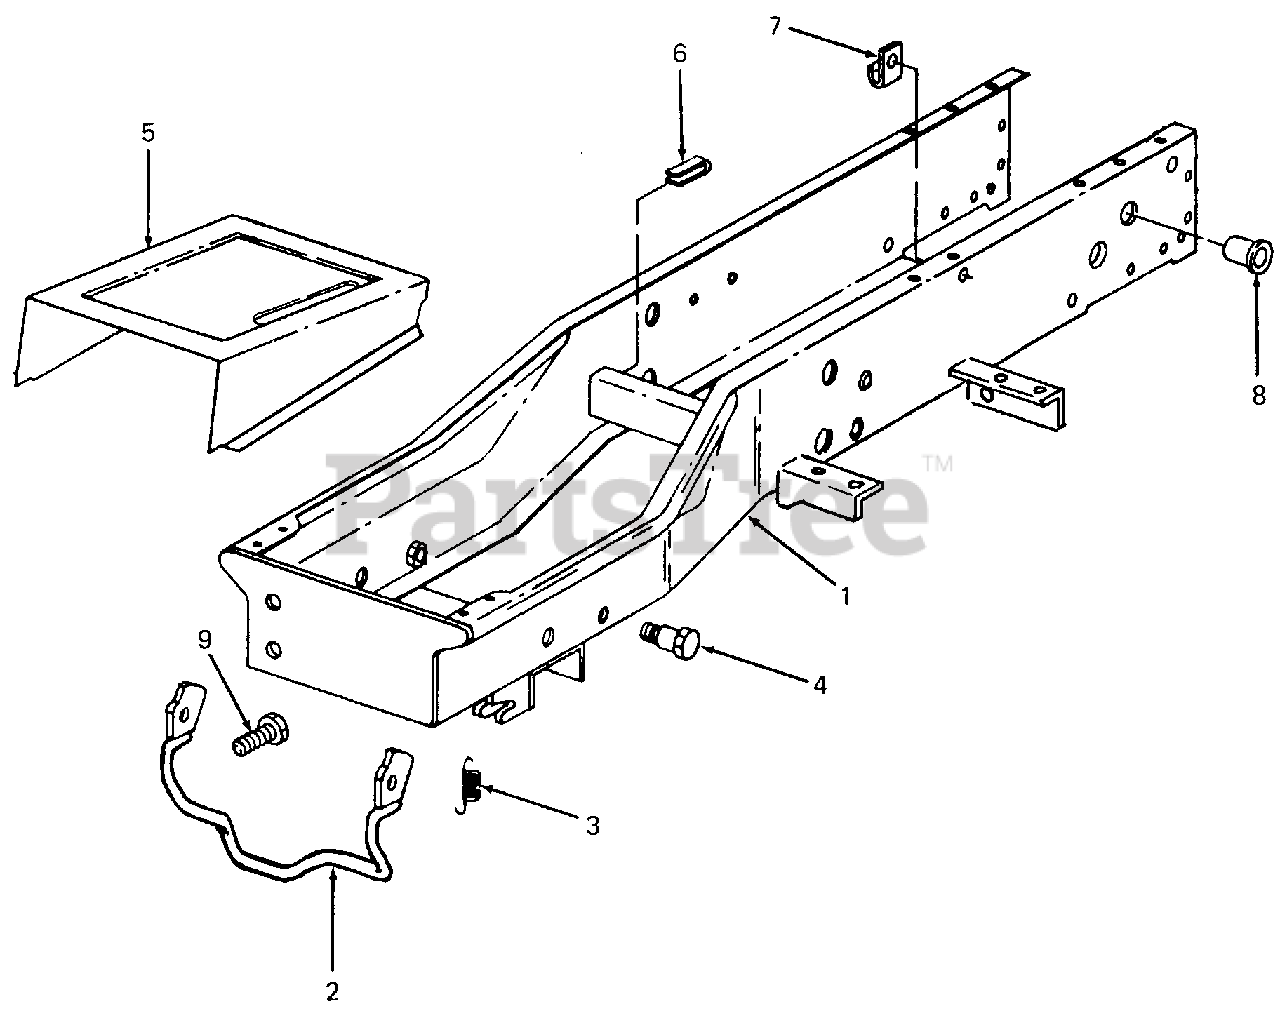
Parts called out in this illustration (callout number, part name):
1	Frame Assy
3	Spring, Latch
4	Bolt, Shoulder
5	Cover, Frame w/Graphic
6	Clip, Steering Bracket Cable
7	Clip, Cable
8	Bushing, Snap
9	Screw, Adjustment, 1/2-20 X 1.0 Lg GR5
